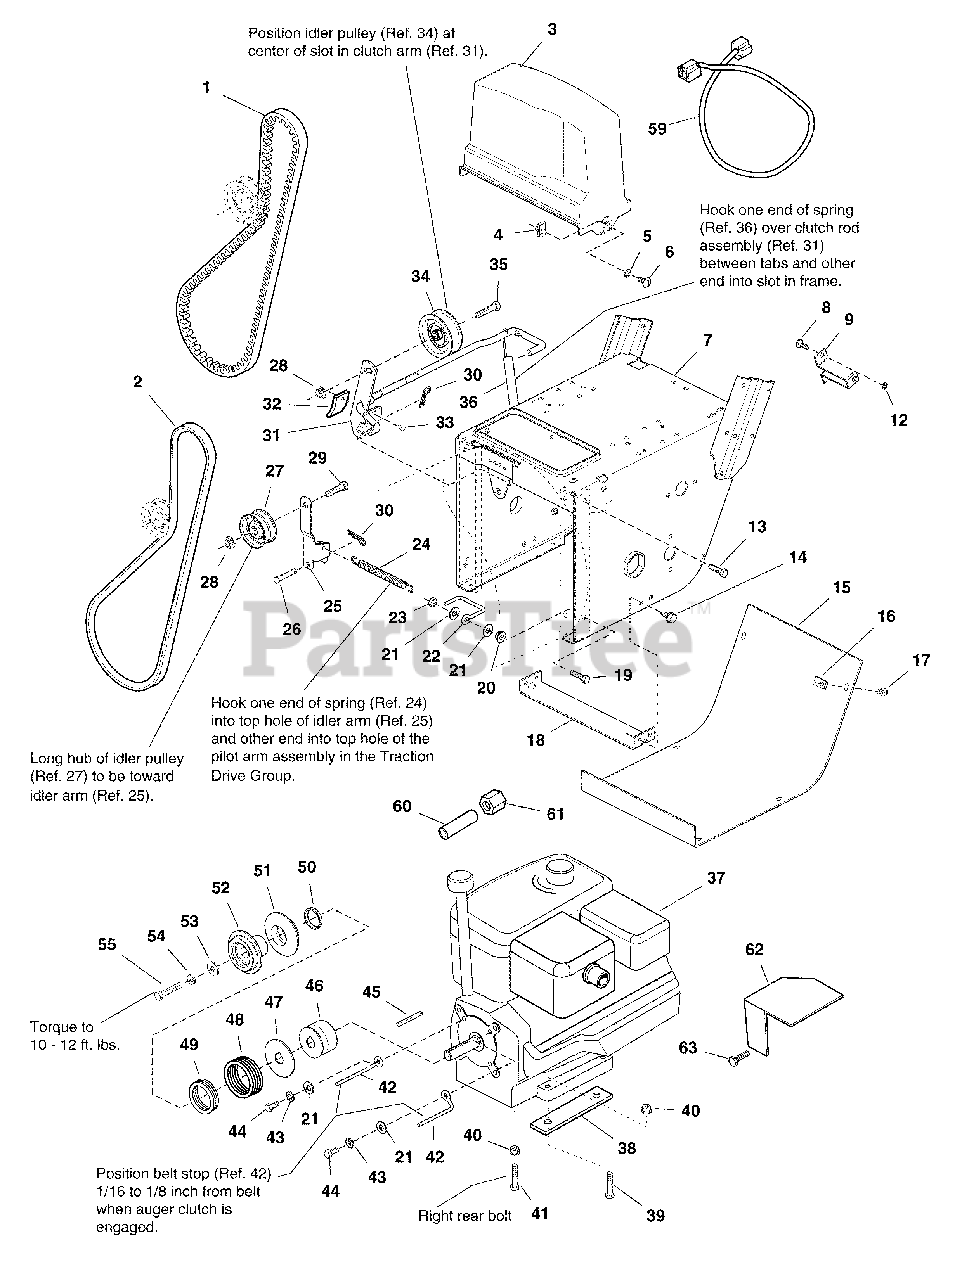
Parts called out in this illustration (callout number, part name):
1	BELT, Auger Drive
2	BELT, Traction
3	GUARD, Belt
4	NUT, Speed, 5/16-18
5	LOCKWASHER, Ext. Tooth, 5/16
6	SCREW, Truss Head, 5/16-18 x 3/4
7	FRAME, Main
8	CARRIAGE BOLT, 1/4-20 x 3/4
9	SUPPORT, Clutch Cable
10	WASHER, 1/4
11	LOCKWASHER, Spring, 1/4
12	NUT, Hex Washer, 1/4-20
13	CAPSCREW, Hex Head, Whizlock, 5/16-18 x 3/4
14	CAPSCREW, Hex Head, Taptite, 5/16-18 x 3/8
15	COVER, Bottom
16	NUT, Speed, 1/4-20
17	CAPSCREW, Hex Head, Taptite,1/4-20 x 1/2
18	SUPPORT, Tie Bar
19	CAPSCREW, Hex Head, Whizlock, 5/16-18 x 1-1/4
20	NUT, Hex, Whizlock, 5/16-18
21	WASHER, 11/32 x 3/4
22	GUIDE, Belt
23	NUT, Hex, Centerlock, 5/16-18
24	SPRING, Idler
25	ARM, Idler, Traction
26	PIN
27	PULLEY, Idler
28	NUT, Hex Flange Whiz Lock 3/8-16
29	CAPSCREW, Hex Head, 3/8-16 x 1-1/2
30	PlN, Hair 5/64 x 1-3/16
31	CLUTCH ROD & BRAKE ASSEMBLY
34	ASSEMBLY, Pulley Auger Drive
35	CAPSCREW, Hex Head, 3/8-16 x 1-3/4 Black
36	SPRING, Extension
38	SUPPORT, Engine Riser
39	CAPSCREW, Hex Head, 5/16-18 x 2-1/2, Black
40	NUT, Hex Flange, 5/16-18
41	CAPSCREW, Hex Head, 5/16-18 x 2-1/2, Black
42	GUIDE, Belt
43	LOCKWASHER, 5/16
44	CAPSCREW, Hex Head, 5/16-24 x 3/4
45	KEY, Parallel, 3/16 x 13/16 x 7/8
46	PULLEY, Traction
47	WASHER, Thrust
48	SPRING, Compression
49	SPRING, Compression
51	PULLEY, Drive
52	PULLEY, Drive
53	WASHER,13/32 x 1
54	LOCKWASHER, Spring, 3/8
55	CAPSCREW, Hex Head, 3/8-24 x 1-1/2
59	CORD, Electric, 3 Prong (Not a Service Part)
60	PIPE, Oil Drain
61	CAP, Hex, 1/2 x 18 NPT
62	GUARD, Muffler
63	CAPSCREW, Hex Washer Head, Taptite, #10-24 x 1/2
